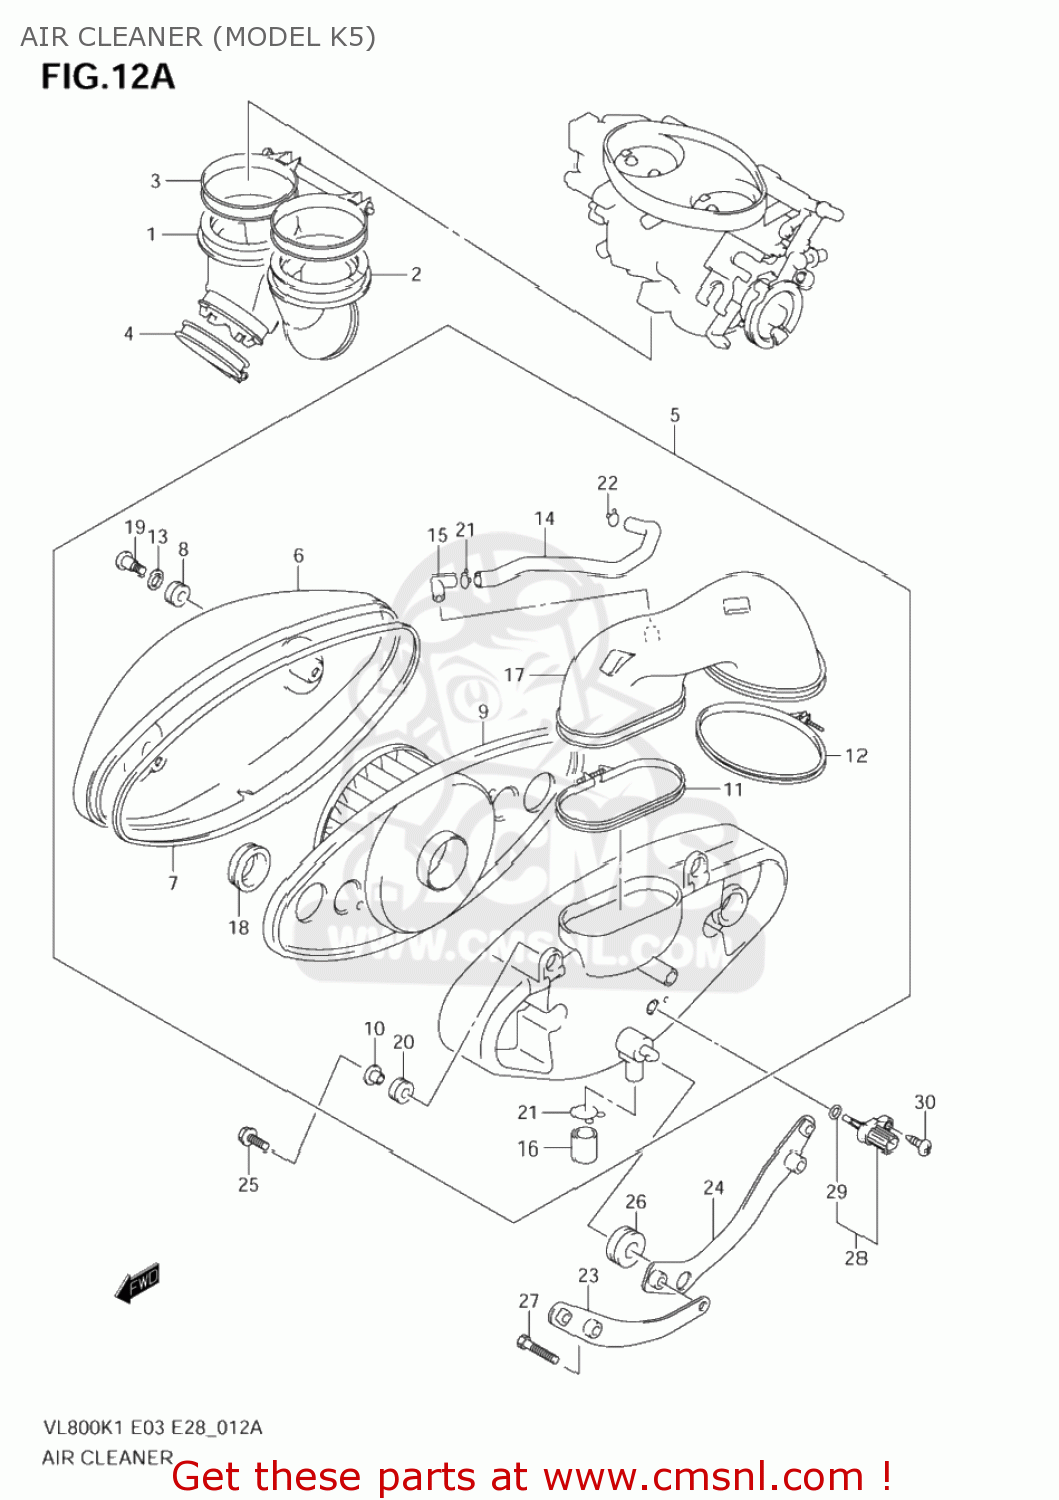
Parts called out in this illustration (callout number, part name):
1	PIPE,INTAKE NO.1
2	PIPE,INTAKE NO.2
3	CLAMP,INTAKE PIPE
4	CLAMP,INTAKE PIPE
5	CLEANER ASSY,AIR
6	CAP,AIR CLEANER
7	GASKET (NAS)
8	CUSHION
9	FILTER ASSY
10	COLLAR,CLEANER CASE
11	CLAMP
12	CLAMP
13	WASHER
14	TUBE,BREATHER
15	JOINT
16	PLUG
17	TUBE,OUTLET
18	TUBE,INLET
19	SCREW(6X20)
20	CUSHION
21	CLIP
22	CLAMP
23	BRACKET,AIR CLEANER FR
24	BRACKET,AIR CLEANER RR
25	SCREW(6X20)
26	CUSHION
27	BOLT
28	SENSOR,AIR TEMP
29	O RING
30	SCREW
